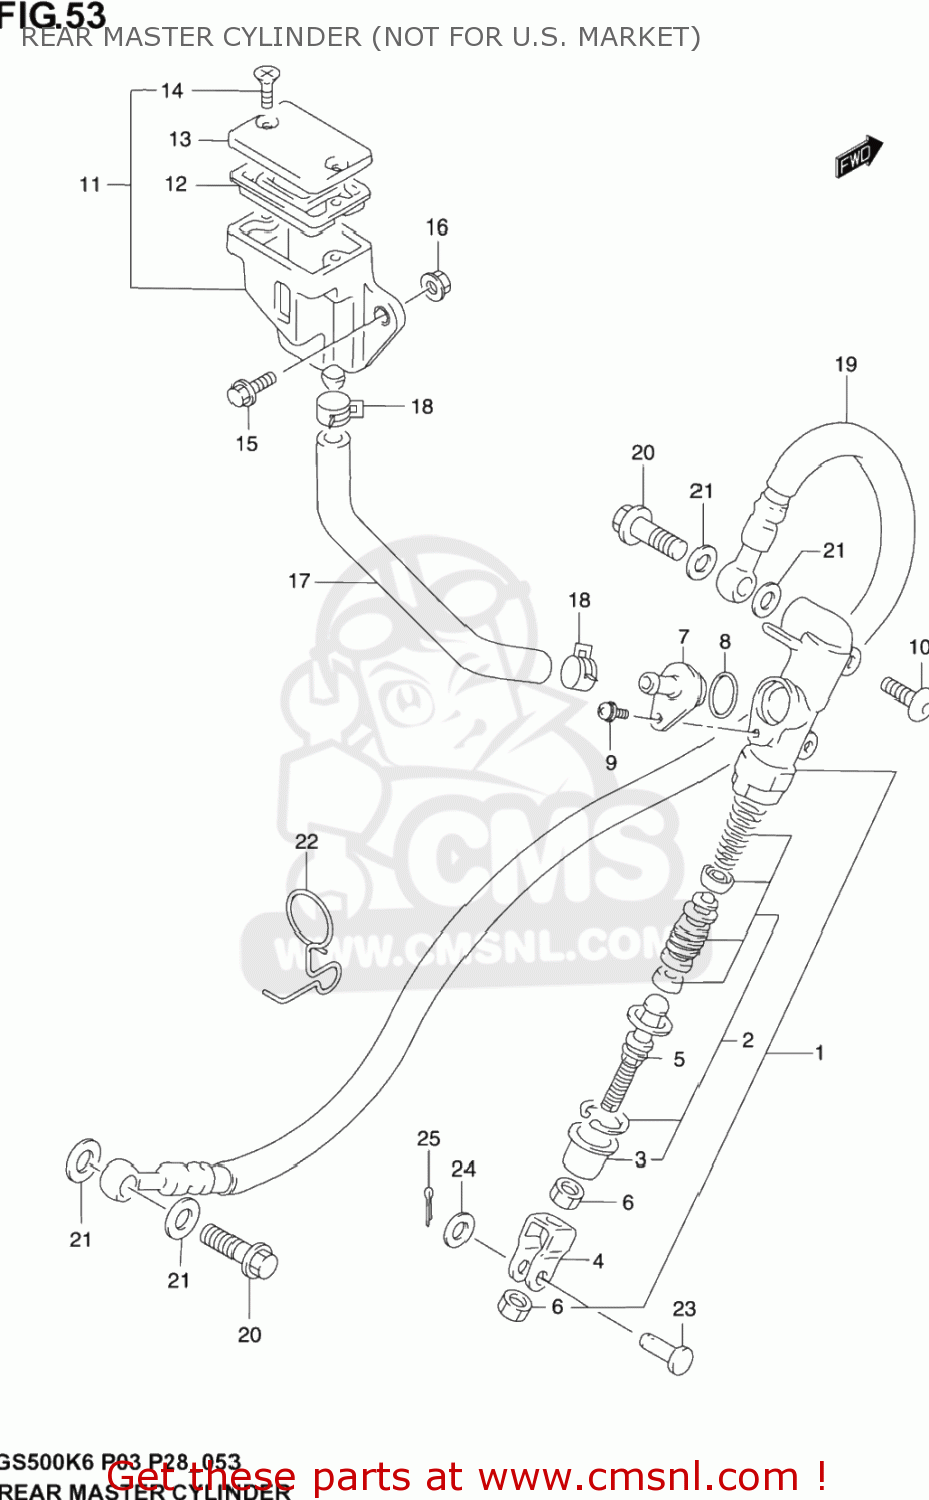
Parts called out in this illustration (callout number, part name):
1	CYLINDER ASSY,RR MASTER
2	PISTON/CUP SET
3	BOOT
4	YOKE
5	ROD,PUSH
6	NUT
7	CONNECTOR
8	O RING
9	SCREW
10	SCREW(6X25)
11	TANK ASSY,RR RESERVOIR
12	DIAPHRAGM
13	CAP
14	SCREW
15	BOLT
16	NUT
17	HOSE,RESERVOIR TANK
18	CLIP
19	HOSE,RR BRAKE
20	BOLT UNION
21	WASHER
22	GUIDE,RR BRAKE HOSE
23	PIN
24	WASHER
25	PIN, COTTER
